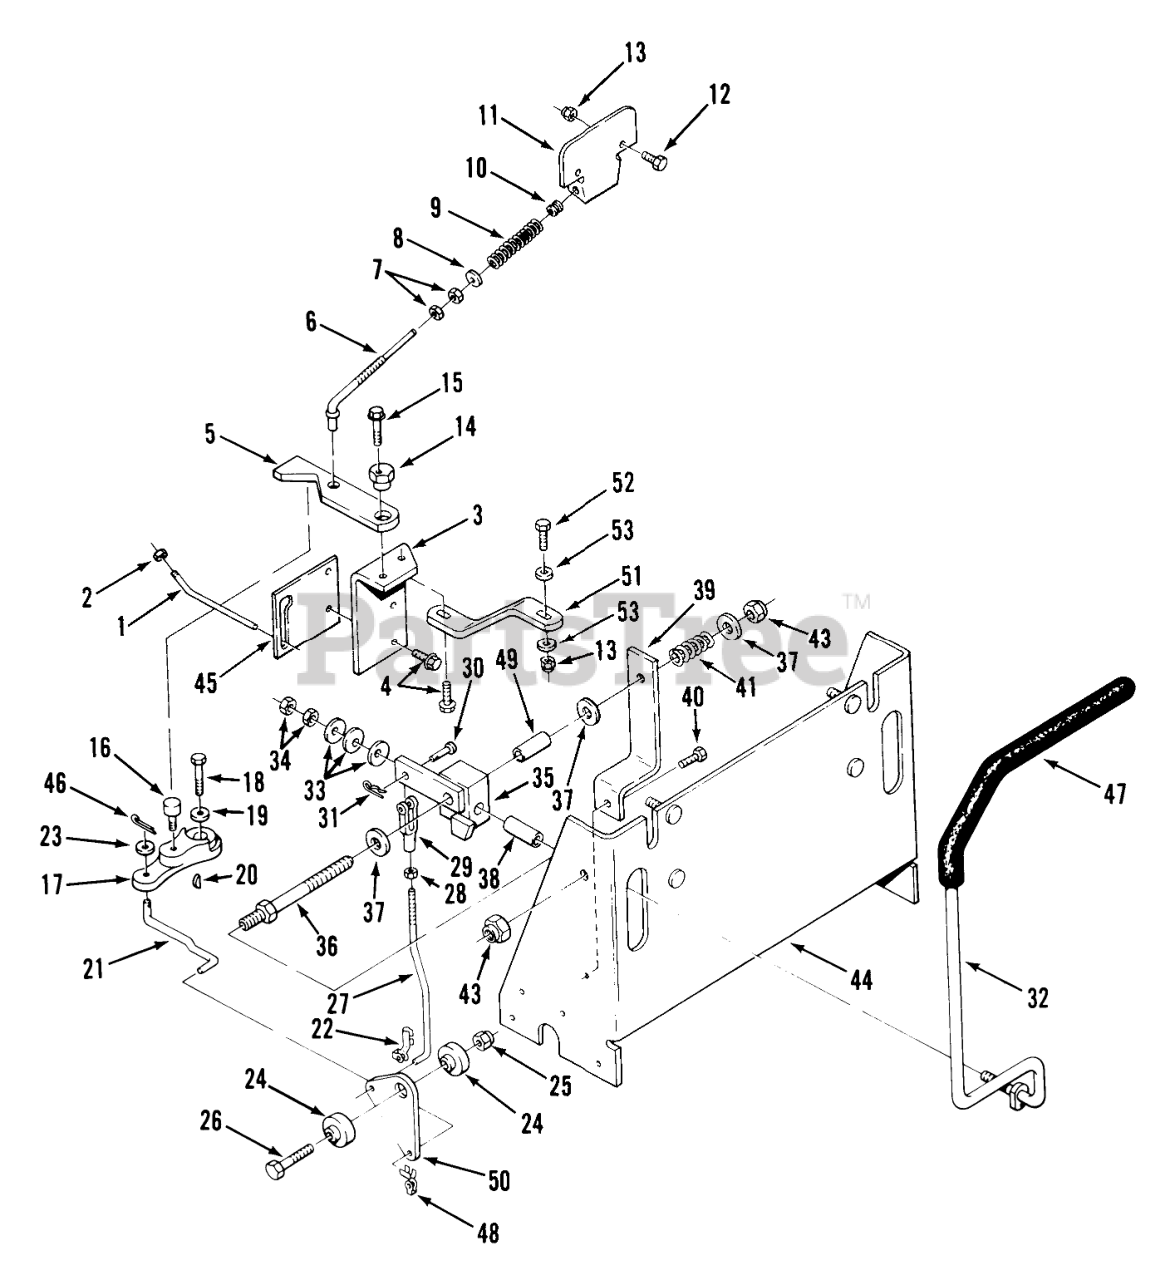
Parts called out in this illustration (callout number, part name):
1	LEVER-TOW VALVE
2	Nut
3	Bracket RH
3	Bracket LH
4	Bolt
5	Arm
6	ROD-NEUTRAL RETURN
7	Nut
8	Washer
9	SPRING COMPRESSION
10	NYLINER BUSHING
11	Bracket
12	Bolt
13	Nut
15	Bolt
16	BEARING-CAM ROLLER
17	ARM-SPEED CONTROL
17	Control Arm LH
18	Bolt
19	WASHER
20	KEY WOODR 1/8X1/2 DI
21	LINK-R.H.
21	LINK-L.H.
22	CLIP-CLEVIS L.H.
24	SPACER-CLUTCH LINK
25	NUT
26	Bolt
27	ROD-HYDRO CTRL. ADJ.
28	Jam Nut 1/4-28
30	Pin
32	R/H STRG LEVER B
32	Steering Lever LH
33	SPRING-BELLVILLE
34	Jam Nut
35	Lever Pivot RH
35	Lever Pivot LH
36	SHAFT-PIVOT
37	Washer
38	BUSHING-STR LVR PVT
39	Bracket-Retainer
40	Screw
41	SPRING
43	Nut
44	Lever Support
45	PLATE-TOW VALVE L
46	Cotter Pin
47	Grip
48	CLIP-CLEVIS R.H.
48	CLIP-CLEVIS L.H.
49	BUSHING
50	PLATE-CONTROL PIV
52	Bolt
53	WASHER 5/16 SAE
